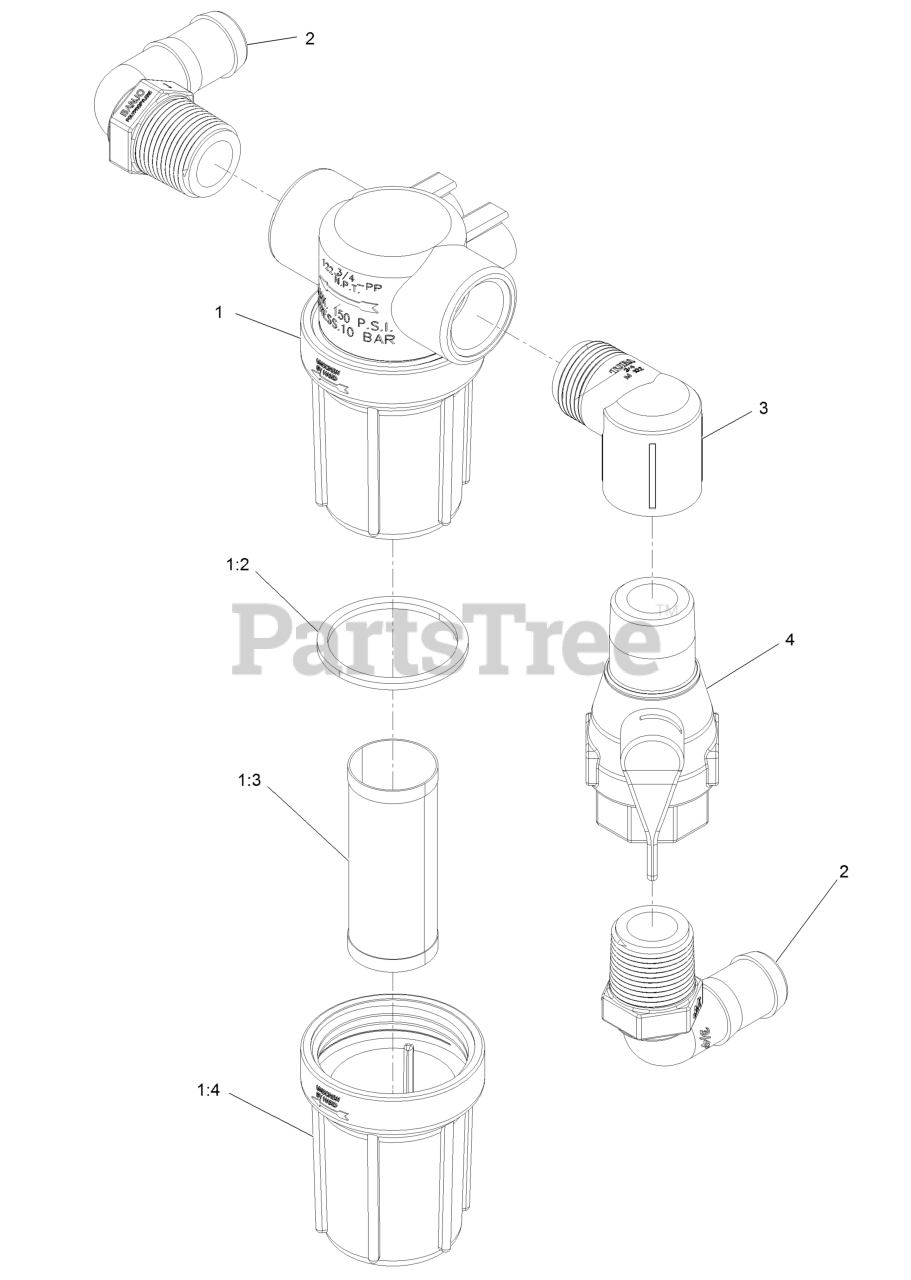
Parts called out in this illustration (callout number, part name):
1	Strainer-Line
1:2	Gasket-Head, Line Strainer
1:3	Screen-Strainer, 30 Mesh SS
1:4	Bowl-Strainer
2	Elbow-Hosebarb
4	Valve-Ball
